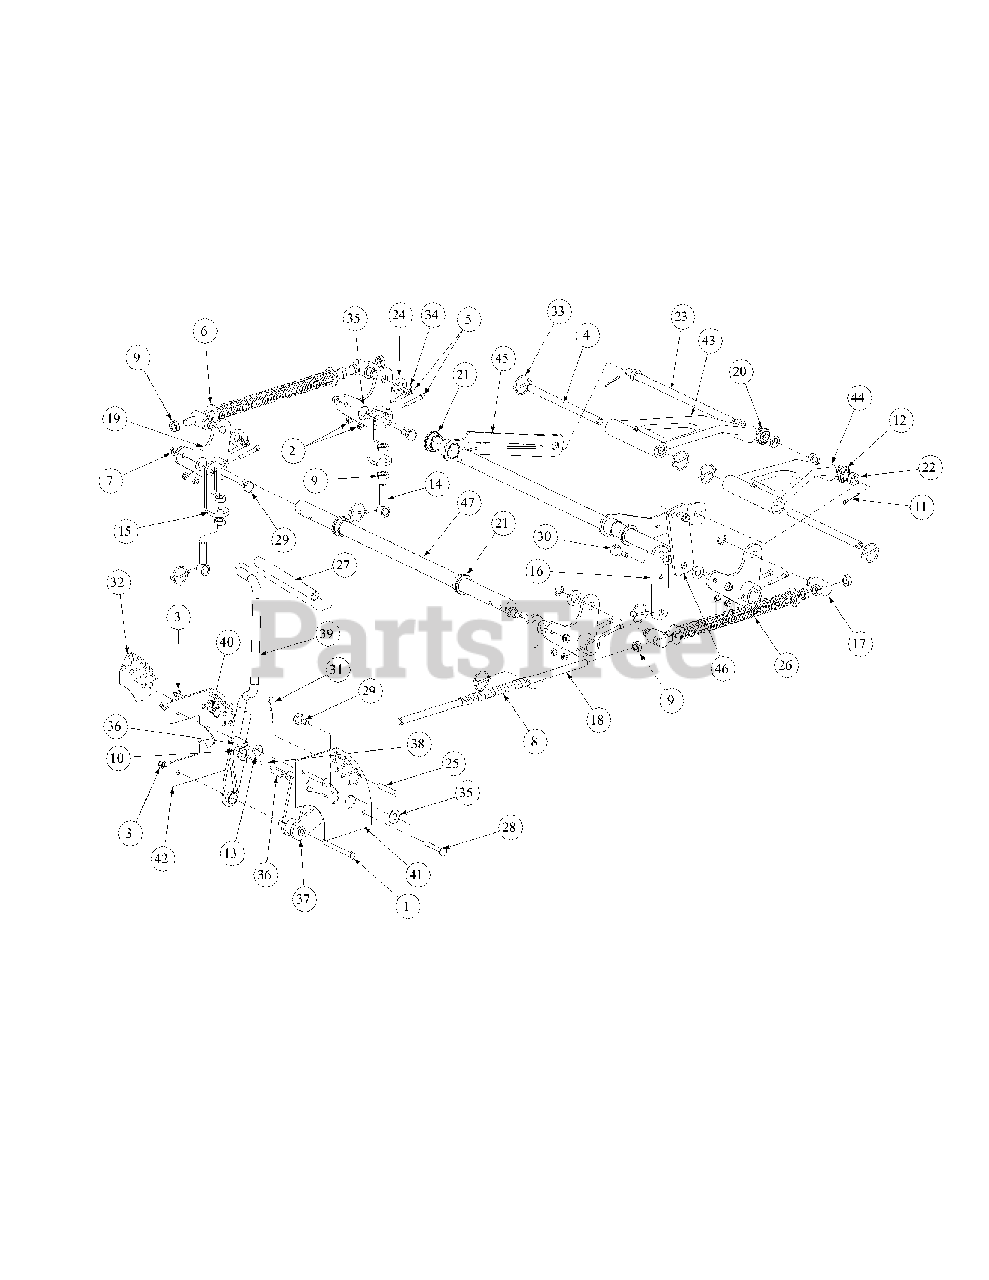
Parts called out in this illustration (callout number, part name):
1	Hex Cap Screw, 3/8-16, 3.75
2	Nut, 5/16-18, Nylock
3	Nylock Insert Lock Nut, 3/8-16
4	Deck Lift Link Rod
5	Socket Head Screw, 5/16-18 x 2
6	Flat Washer, 5/8
7	Hex Nut, Flange Lock, 3/8-16
8	Hose, 5/8 ID 13/16 OD, 8" LG
9	Jam Nut, 5/8-11
10	Flat Washer, .06, .776, 1.25
11	Cotter Pin, 3/16 x 1-1
12	Male Rod End, Right Hand
13	Idler Washer
14	Eye Bolt, 5/8ID
15	Eye Bolt Mount Link, 5/8 ID
16	Deck Link
17	Ferule Lift
18	Lift Connector Rod
19	Bellecrank Weldment Lift
20	Jam Nut, 5/8-18
21	Hex Flange Bearing, 1.25 ID
22	Spacer, .630 x 1.06 x .440
23	Front Lift Link, Rod Mount
24	Spacer, .812 ID x .218 Lg.
25	Clevis Pin, .437 Dia. x 2.625 Lg.
26	Lift Compression Spring
27	Lift Handle Grip
28	Carriage Bolt, 3/8-16, 2.75
29	Shoulder Screw, 0.625 OD x .437 Lg.
30	Shoulder Screw, 0.625 OD x .830 Lg.
31	Cotter Pin, .148 x 3.00
32	Decal Height Indicator
33	Linch Pin, 3/16 Dia.
34	E Clip, 3/4 Dia.
35	Nylon Flat Washer, 5/8
36	Spacer, .39 ID x .63 OD x 1.442
37	Lift Pivot Assembly
38	Lift Handle Spring
39	Lift Handle Assembly
40	Shoulder Screw, .50 OD x 0.270, 3/8-16
41	Outer Lift Index Plate
42	Inner Lift Index Plate
43	Trail Link Assembly, w/ brg Right Hand
44	Trail Link Assembly, w/ brg Left Hand
45	Front Frame Strut Assembly
46	Lift Link Adjustment
47	Deck Lift Shaft
